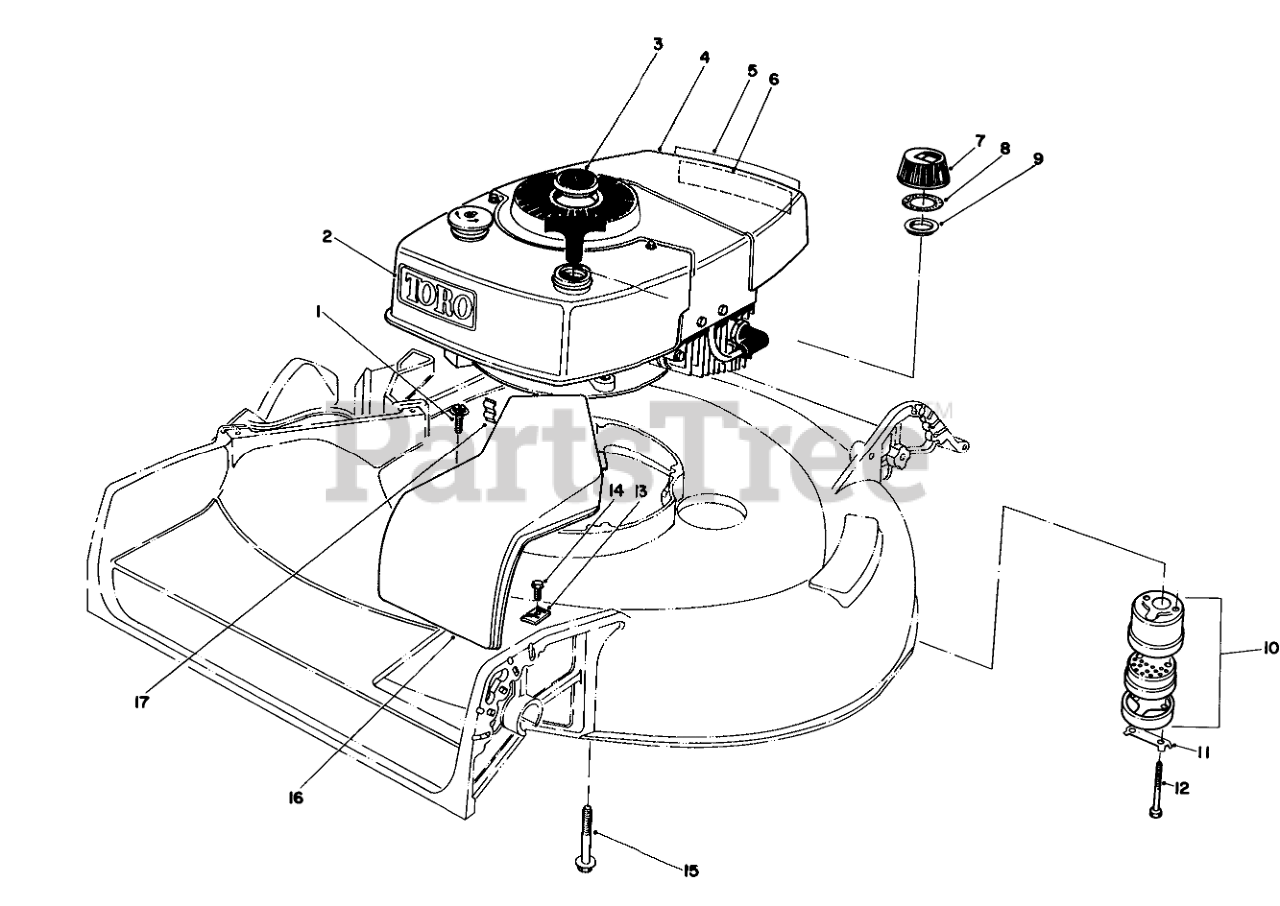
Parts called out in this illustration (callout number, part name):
1	SCREW
2	Decal Tow
3	Plug Button
4	Engine
5	Decal-Primer
6	Decal Maintenance
7	Fuel Cap Assembly (Incl. Ref. #8 & 9)
8	GASKET
9	GAS CAP BAFFLE
10	Muffler Assembly (Incl. Ref. #11 & 12)
11	CLIP - LOCKING
12	SCREW-HH
13	Cable Clamp
14	SCREW-HWHTF
15	3/8-16 X 2-3/4 CAPSCR
16	Cow-Belt
17	Clip Conduit
